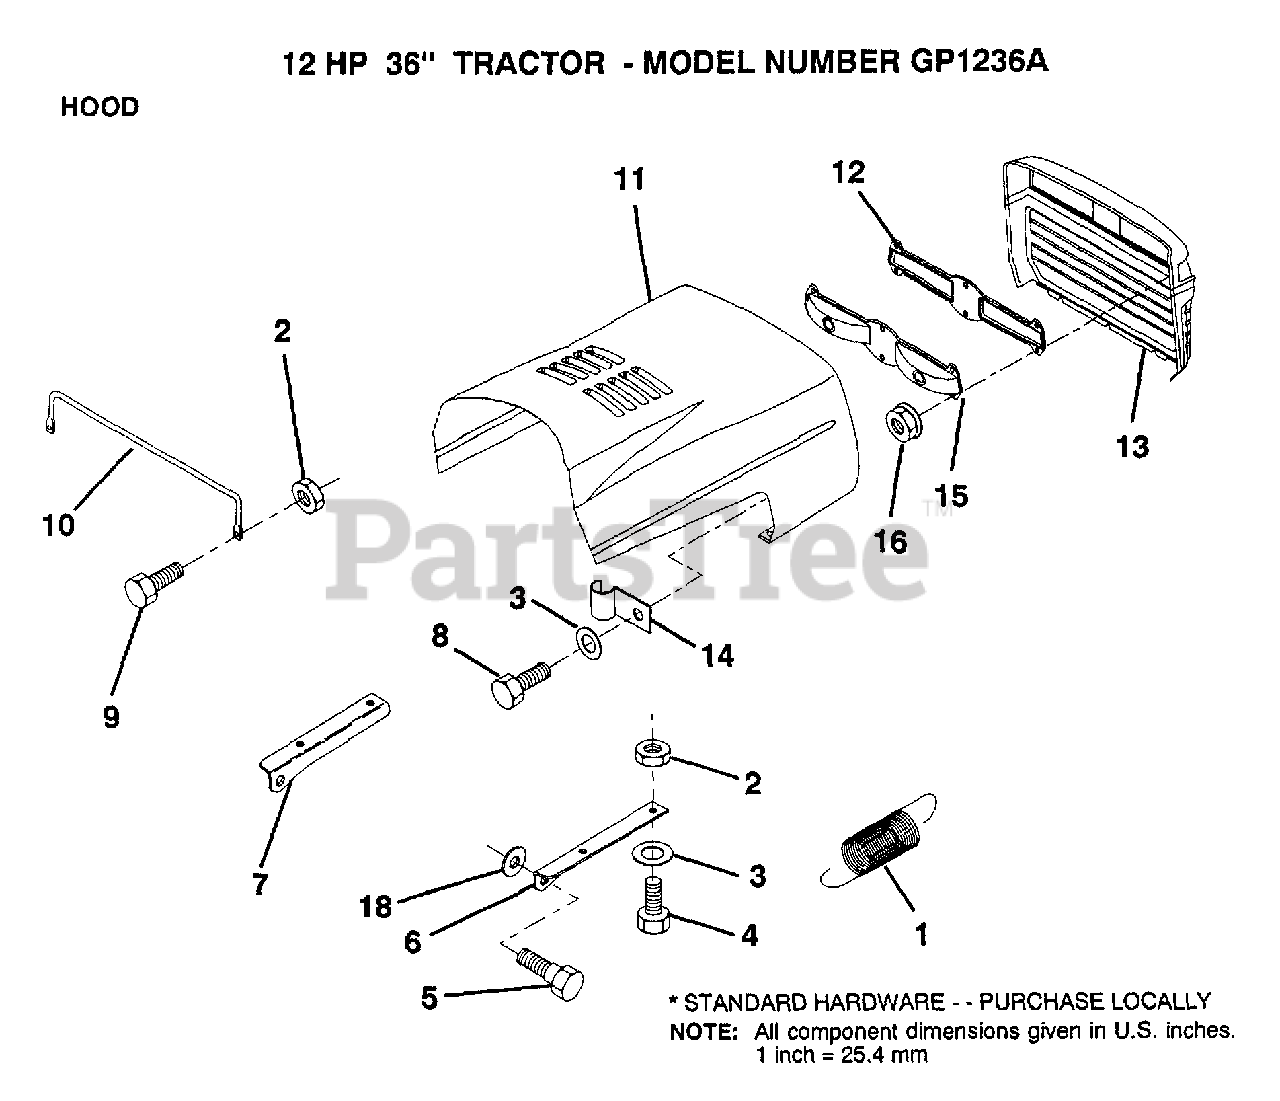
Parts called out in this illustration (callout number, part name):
1	EXT SPRING
2	NUT
3	WASHER
4	BOLT
6	BRKT HOOD RH
7	BRKT HOOD LH
10	"BRACE,HOOD"
11	HOOD
16	NUT
18	NUT
